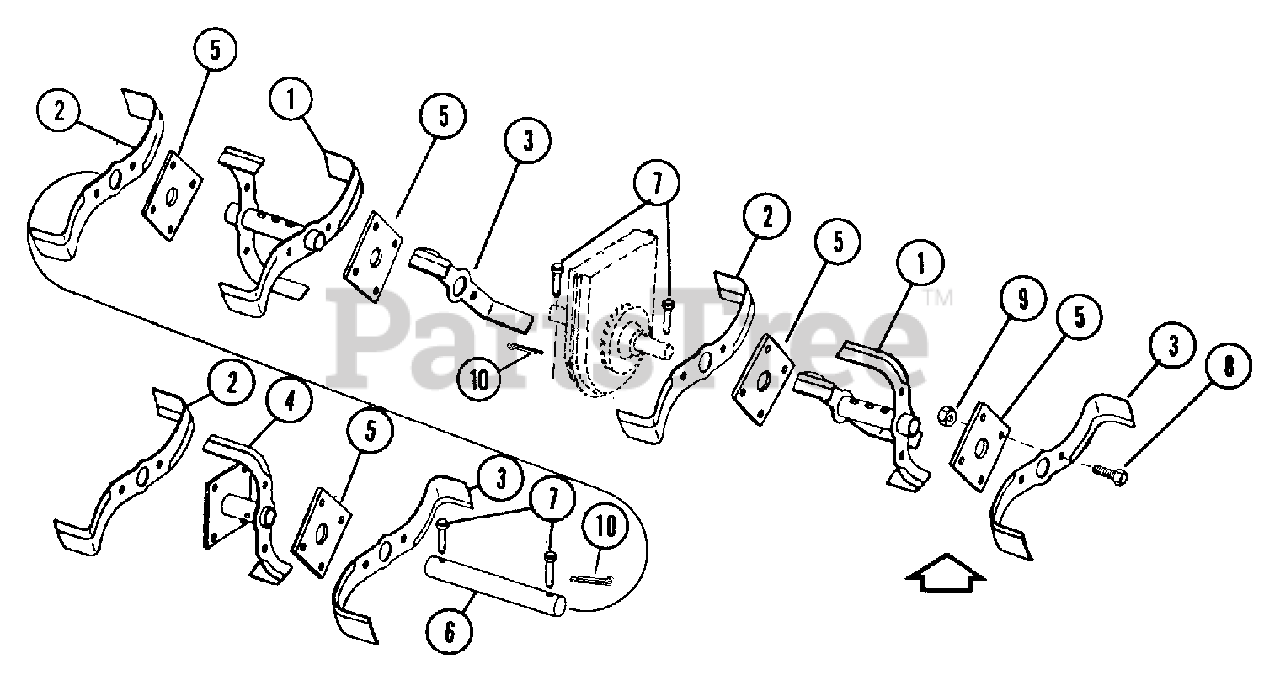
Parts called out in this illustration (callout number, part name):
1	INNER TINE
2	L H TINE
3	R H TINE
4	TINE EXTENTION
5	TINE PLATE
6	SHAFT EXTENSION
7	CLEVIS PIN
8	BLT-HEX .44-14X1.00 GR5
9	NUT-LK-TOP .437-14 GR C PL
10	PIN-COTR .12X1.0 PL
